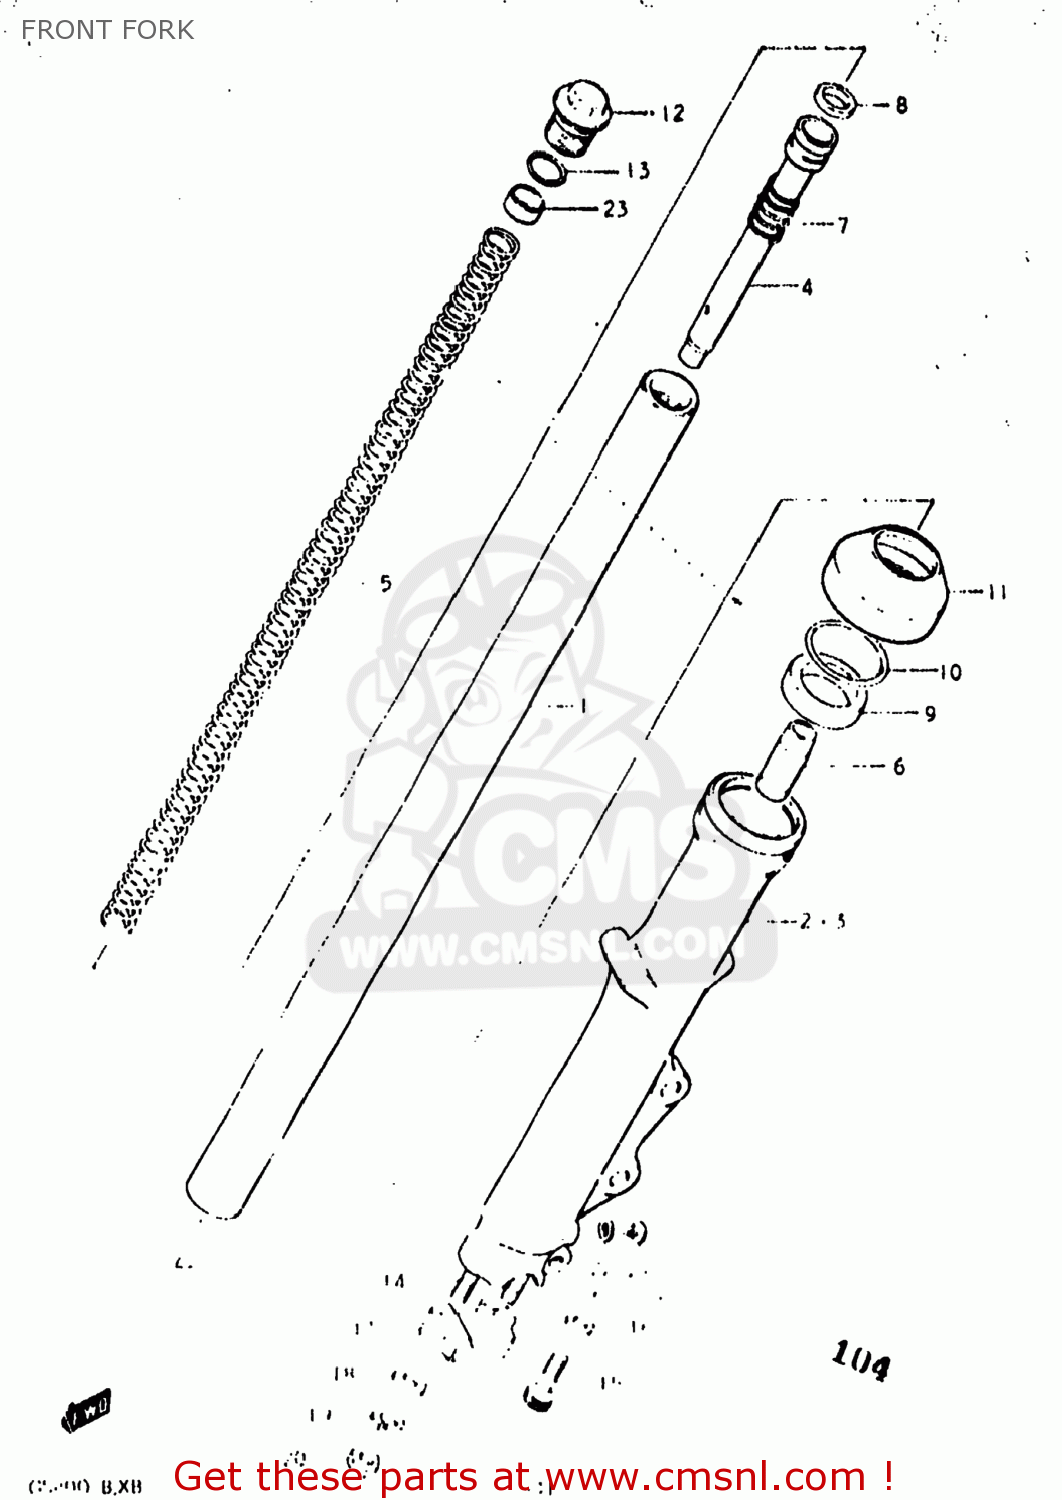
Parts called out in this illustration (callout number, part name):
0	DAMPER ASSEMBLY,LEFT
1	TUBE,INNER
2	TUBE,OUTER,LEFT
3	TUBE,OUTER,RIGHT
4	CYLINDER,FRONT FORK
5	SPRING
6	PIECE,OIL LOCK
7	SPRING,REBOUND
8	RING,PISTON
9	OIL SEAL,FRONT FORK
10	CIRCLIP,FORK OIL SEAL
11	BOOT
12	BOLT,STEERING STEM HEAD
13	O RING
14	STUD 8X25
15	BOLT
16	GASKET (NAS)
17	HOLDER,AXLE
18	WASHER
19	LOCK WASHER
20	NUT
21	SCREW
22	GASKET (NAS)
23	SPACER,FRONT FORK SPRING
